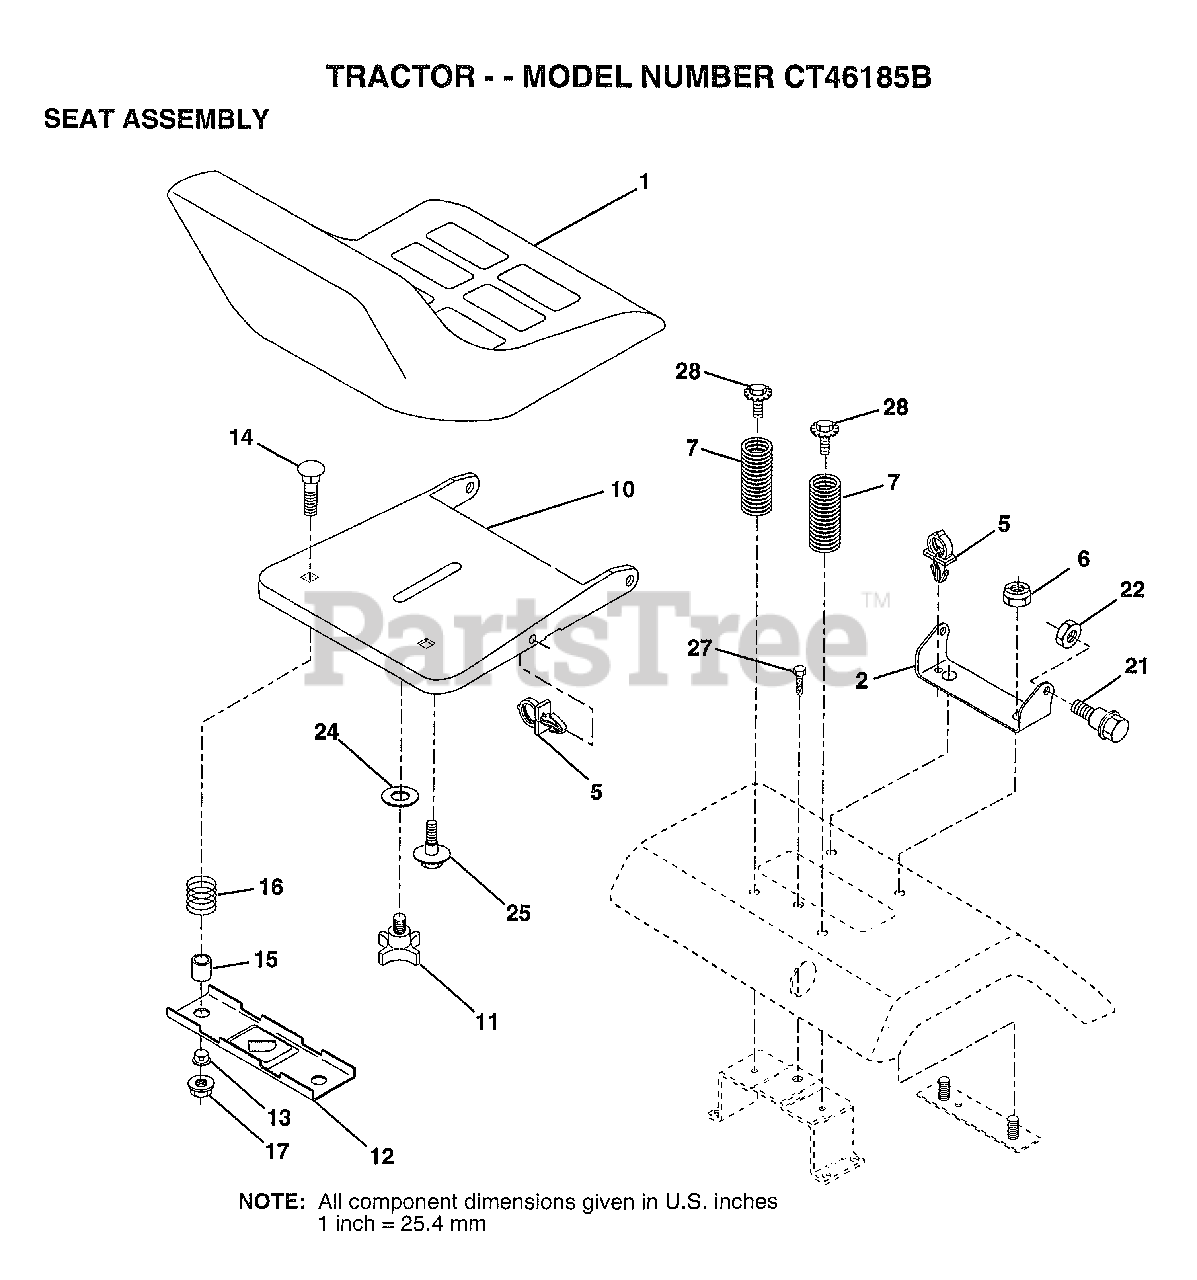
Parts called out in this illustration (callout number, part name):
2	BRACKET PVT SEAT
5	CLIP.PUSH-IN.HING
6	NUT
7	SPRING COMPRESSIO
10	PAN-SEAT
11	"KNOB 1/2"" YT"
12	BRKT SWITCH
13	BUSHING
14	BOLT-RD HD SQ NK
15	SPACER SPLIT
16	SPRING COMPRESSED
21	"BOLT,SHOULDER"
24	WASHER
25	"BOLT,SHOULDER"
27	SCREW LT
28	BOLT.5/16-18.UNC
